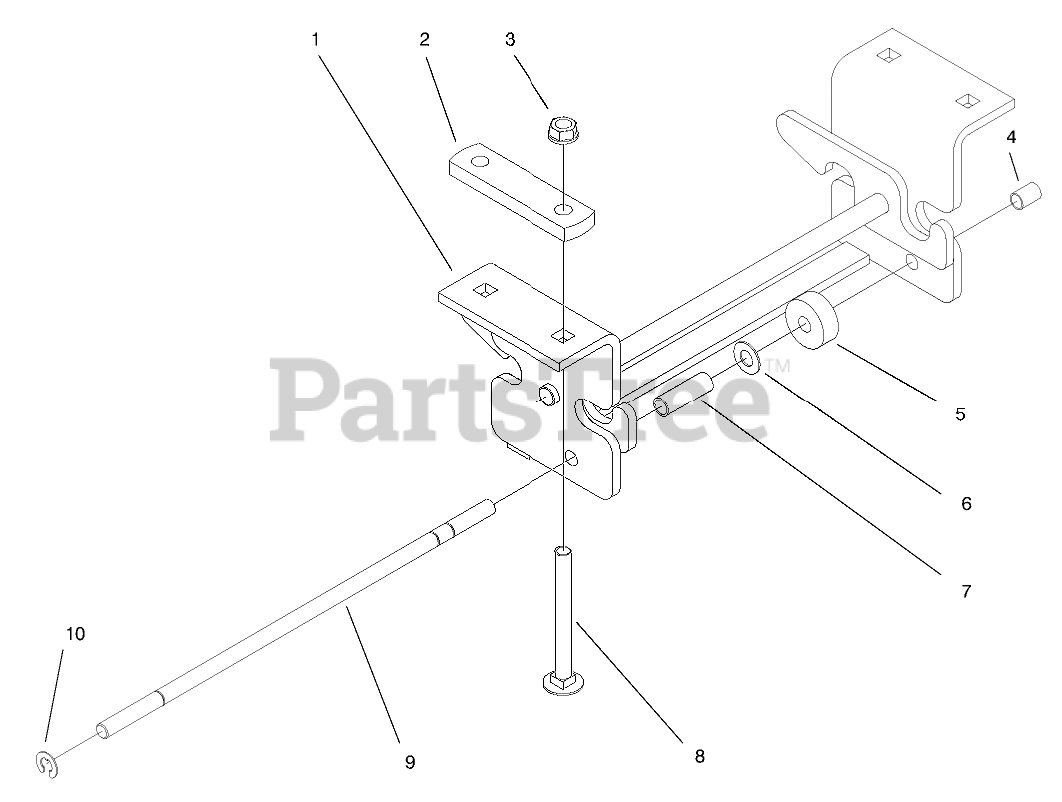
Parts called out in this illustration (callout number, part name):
1	Mounting Bracket ASM
2	BRACKET-REAR LINK MOUNTING
3	NUT-LOCK, SIDE
4	CAP-ROD, PLUNGER
6	WASHER-FLAT
7	SPRING
8	SCREW-CARR
9	ROD-LATCH, HITCH
10	RING-RETAINING
